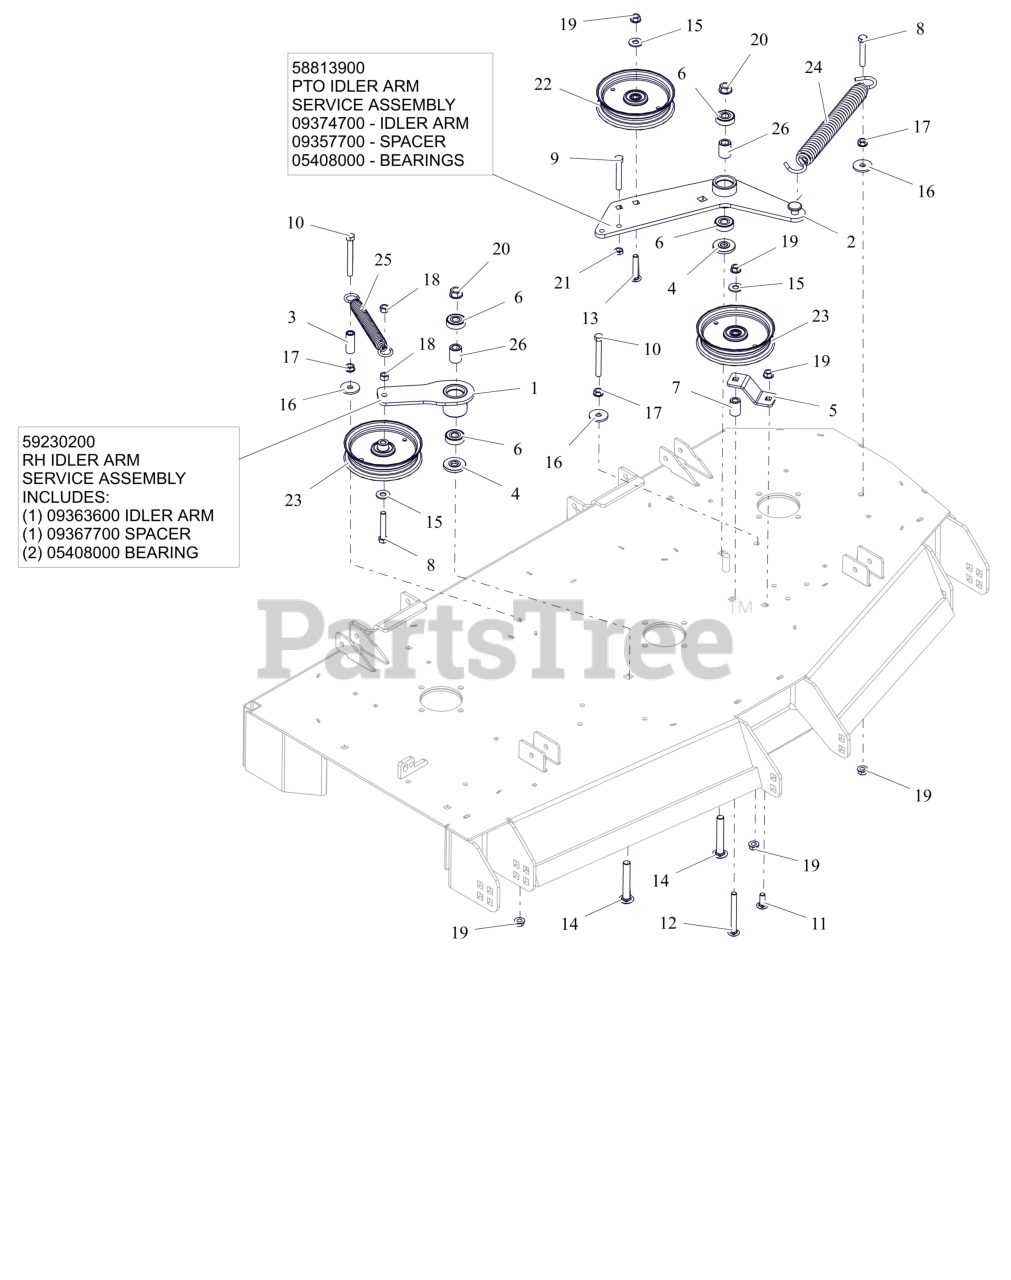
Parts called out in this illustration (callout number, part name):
1	WLDMT, DECK RH IDLER ARM
1	RH IDLER ARM
1	SPACER .510 X .867 X 1.1485
1	BRG-BALL .500X1.38X.437
2	WLDMT, IDLER ARM PT660
2	PTO IDLER ARM
2	SPACER .510 X .867 X 1.1485
2	BRG-BALL .500X1.38X.437
3	SPACER, .375IDX.625ODX1.66 PM
4	SPACER, IDLER ARM
5	PTO FIXED IDLER MTG BRKT -RED
6	BRG-BALL .500X1.38X.437
7	BUSHING, SLV .380X.750X1.190
8	BLT,HEX .38-16X2.25 G5 ZCC
9	BLT, HEX .38-16X2.50 G5 ZCC
10	BLT, HEX .38-16X3.25 G5 ZCC
11	BLT,RHSSN .38-16X1.00 G5 ZCC
12	BLT,RHSSN .38-16X3.50 G5 ZCC
13	BLT,RHSSN.375-16X2.00 G5 ZCC
14	BTL,RHSSN .500-13 X 3.25 G5 ZCC
15	WSHR,FLT .438X1.00X.083 ZCC
16	WSHR,FLT .406X1.375X.135 ZCC
17	NUT, SPNLK-FLG .38-16 G5 ZCC
18	NUT-LK-CTR .38-16 ZC120
19	NUT-LK-CTR-FLG .375-16 GF ZCC
20	NUT-LK-CTR-FLG .500-13 GG ZCC
21	NUT-JAM .375-16 G2 ZCC
22	PULLEY, FLAT IDLER .500 X .375 W/BRG
23	IDLER- FLAT - 5.00" X .75"
24	SPRING, EXTENSION
25	SPRING- EXTENSION
26	SPACER .510 X .867 X 1.1485
